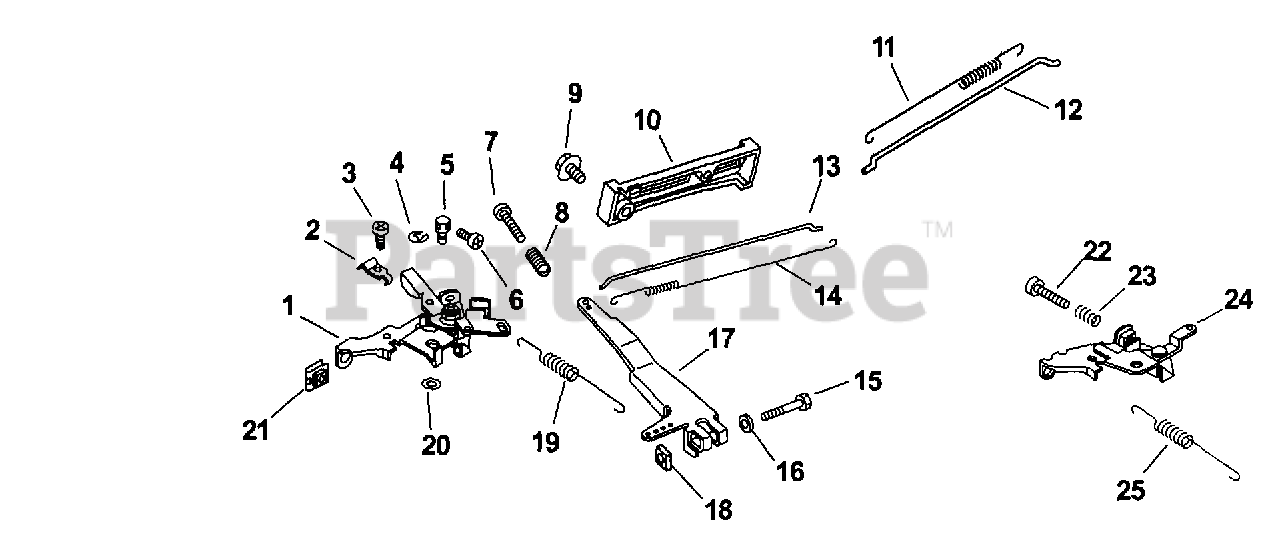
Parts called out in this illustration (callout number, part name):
7	SCREW, PAN HEAD
8	SPRING,COMPRESSION
13	LINKAGE, THROTTLE
14	SPRING, LINKAGE
17	GOV. LEVER ASSY
19	GOVERNOR SPRING
6312607-S	BRACKET, GOVERNOR
